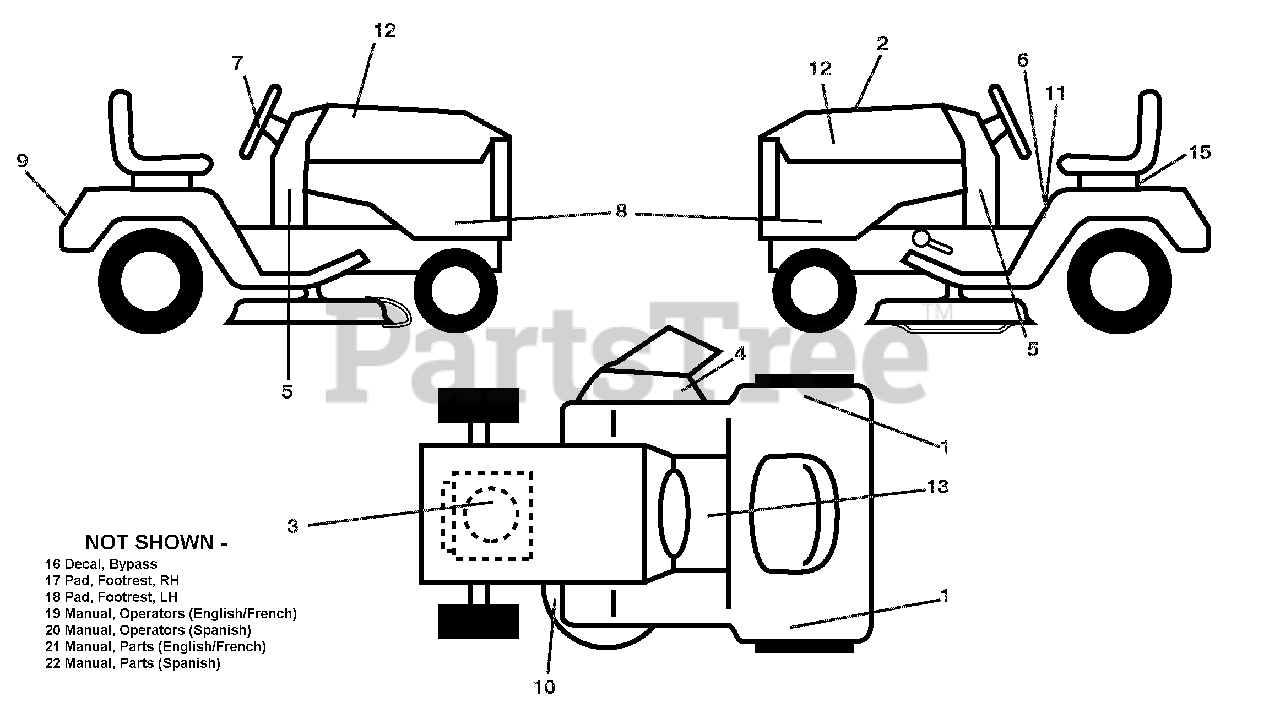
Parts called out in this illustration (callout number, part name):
1	DECAL.FENDER.SIDE.HYDRO
2	DECAL.REPLACEMENT
3	DECAL.ENGINE.HP
4	DECAL DECK/DEFLECT. WARNING
5	DECAL, DASH.LOWER
6	DECAL.WARNING.START
7	DECAL.WHEEL.STEER.ARIENS
8	DECAL.SDPNL.PWRDBY B&S.ARIENS
9	DECAL.FENDER.REAR.ARIENS
10	DECAL.V-BELT.SCH.
11	DECAL.FENDER
12	DECAL.HOOD.LH/RH.
13	Decal, Spark Arrester
15	DECAL.BAT.DAN/POI P/L SYM.WPN
